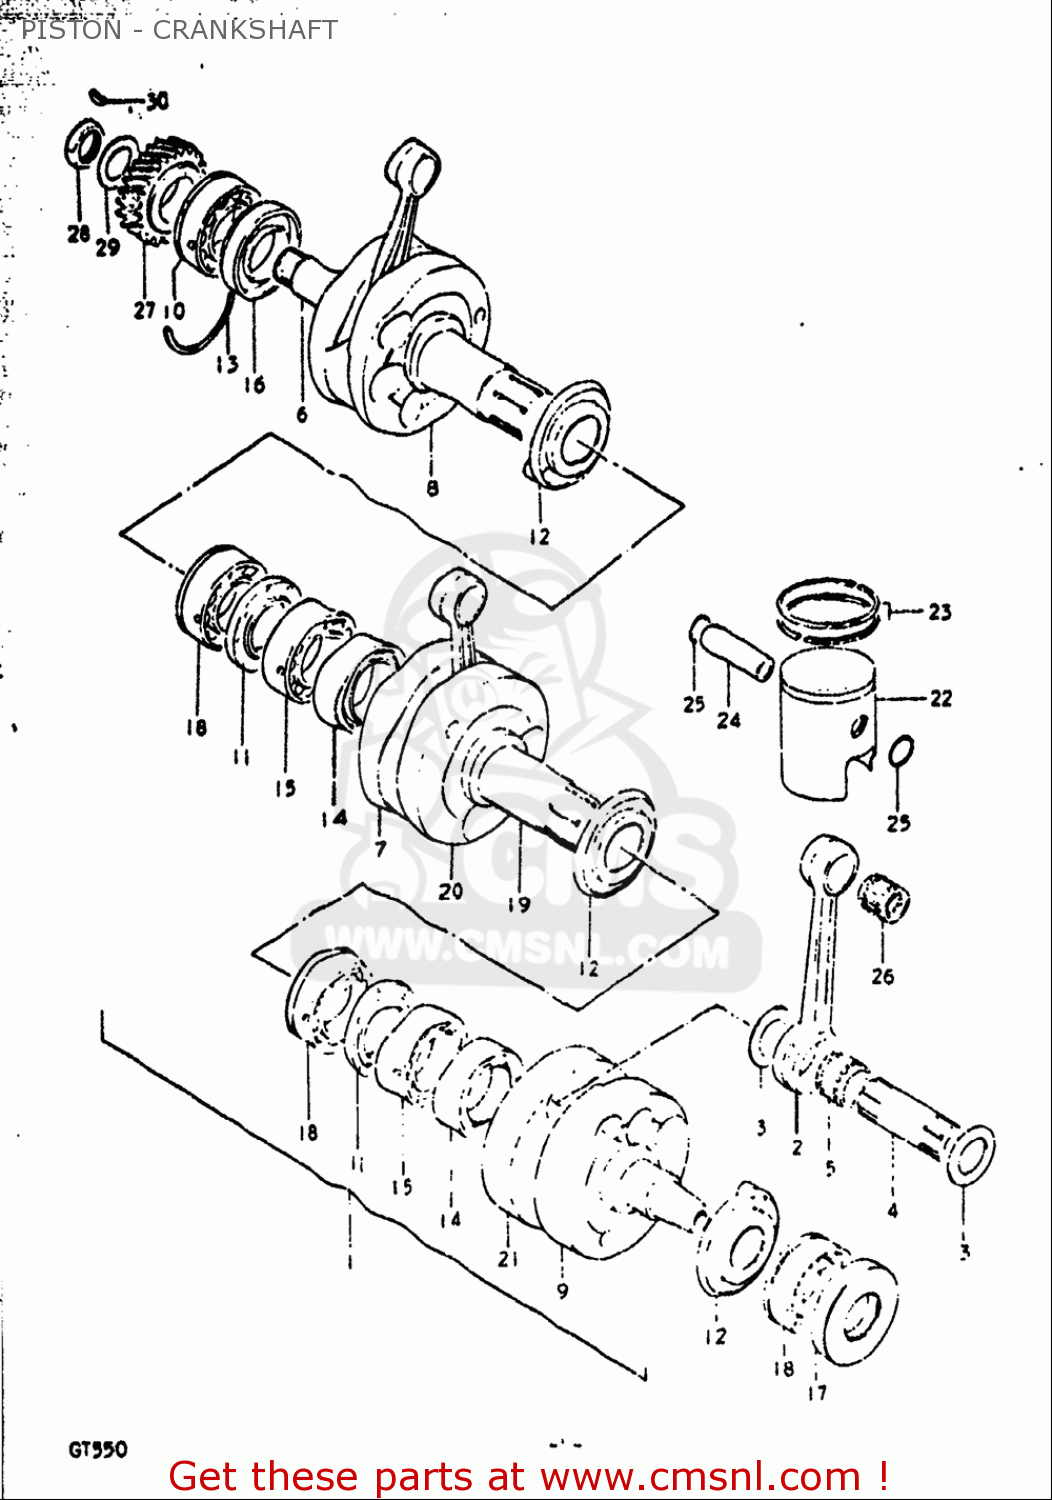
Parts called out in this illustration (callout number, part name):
3	WASHER(22X35X1)
4	PIN,CRANK
5	BEARING(22X28X16)
10	BEARING(25X62X17)
13	C RING
14	SEAL,OIL(38X62X10.5)
15	BEARING(25X62X17)
16	SEAL,OIL(32X62X8)
17	SEAL,OIL(25X62X9.9)
22	PISTON
23	RING SET,PISTON
24	PIN,PISTON
25	RING,SNAP 16MM
26	BEARING(16X21X19.6)
28	NUT (20MM)
29	WASHER
30	KEY
